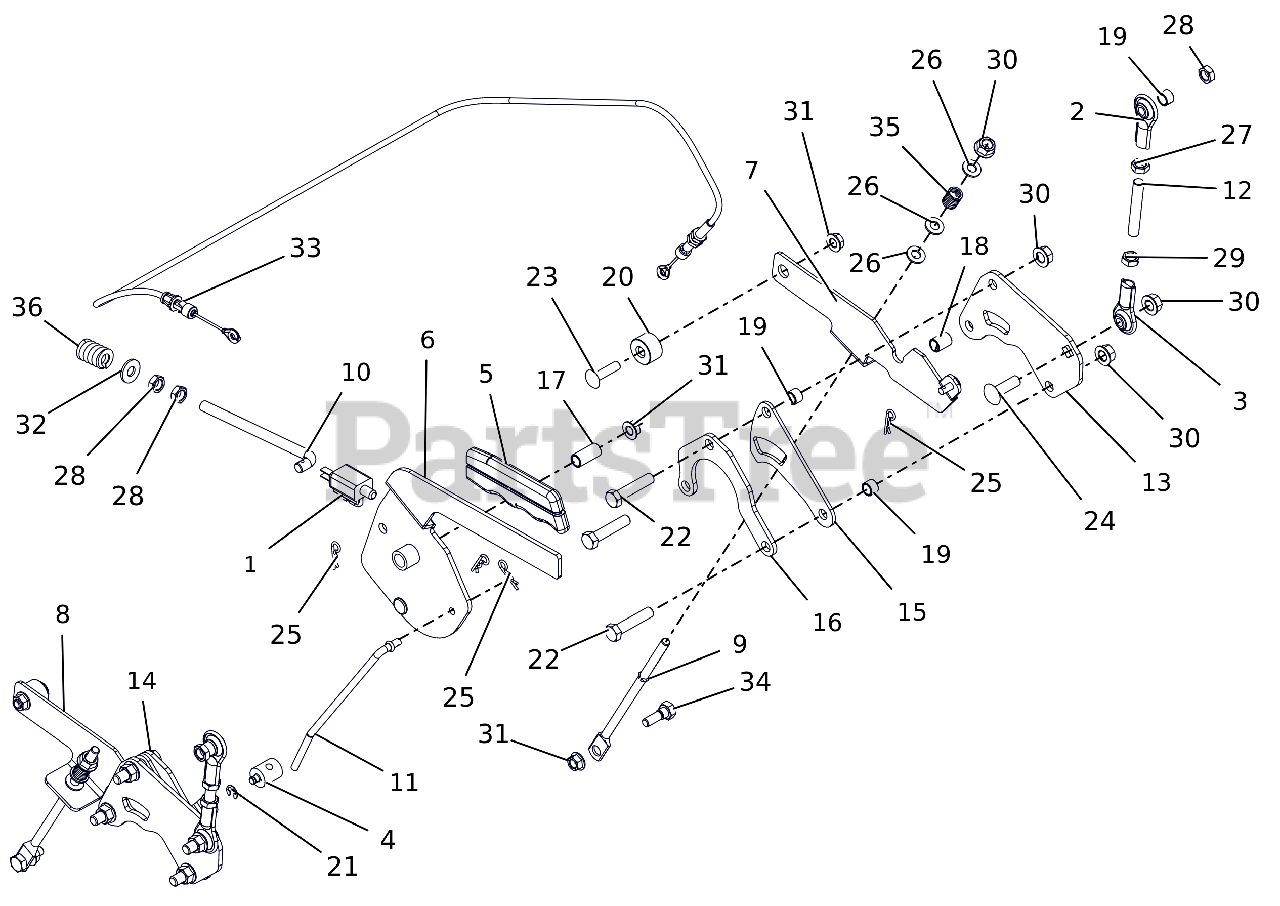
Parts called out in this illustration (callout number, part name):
1	SWITCH, SINGLE POLE N.O.
2	ROD END, .38 RH
3	END, ROD-.38 LH
4	TRUNION, 1/4-20
5	GRIP, PARKING BRAKE (YELLOW)
6	LEVER, PARKING BRAKE
7	ARM, BRAKE - LH (W/PIN)
8	ARM, BRAKE-RH
9	ROD, LINK - TRANSMISSION BRAKE
10	ROD, OVER CENTER
11	ROD, BRAKE LINK
12	ROD, STEERING LINK
13	BRKT, TRANSAXLE STEERING
14	BRKT, SPACER
15	BRKT-SPACER
16	PLATE, REAR REINFORCING
17	BSHG-SLV .385X.500X1.045
18	SPCR, SLV .385X.500X.652
19	SPCR, SLV .385X.500X.350
20	SPCR, FLANGE
21	RG-RTNG-EXT .250X.025
22	@BLT-HEX .38-16X1.75 GR5 YWZC
23	@BLT-RHDSHSQNK.31-18X1.25 G5YZ
24	@BLT-RHDSSQNK .38-16X1.25 G5YZ
25	PIN-HAIR INT .08X.18X1.18 YWZC
26	@WSHR-FL-STL.344X.688X.065YWZC
27	NUT-JAM .375-24 YWZC
28	NUT-HEX-JAM .375-16 YWZC
29	NUT-JAM .375-24 LH YWZC
30	@NUT-LK-TOP-FLG .38-16 YWZC
31	@NUT-LK-TOP-FLG .31-18 YWZC
32	@WSHR-FL-STL.38X.875X.083 YWZC
33	CABLE, BRAKE
34	BOLT,SHLDR .38X.25 -.31-18X.75
35	SPRING, COMPRESSION
36	SG-COMP .187X.56X1.62
